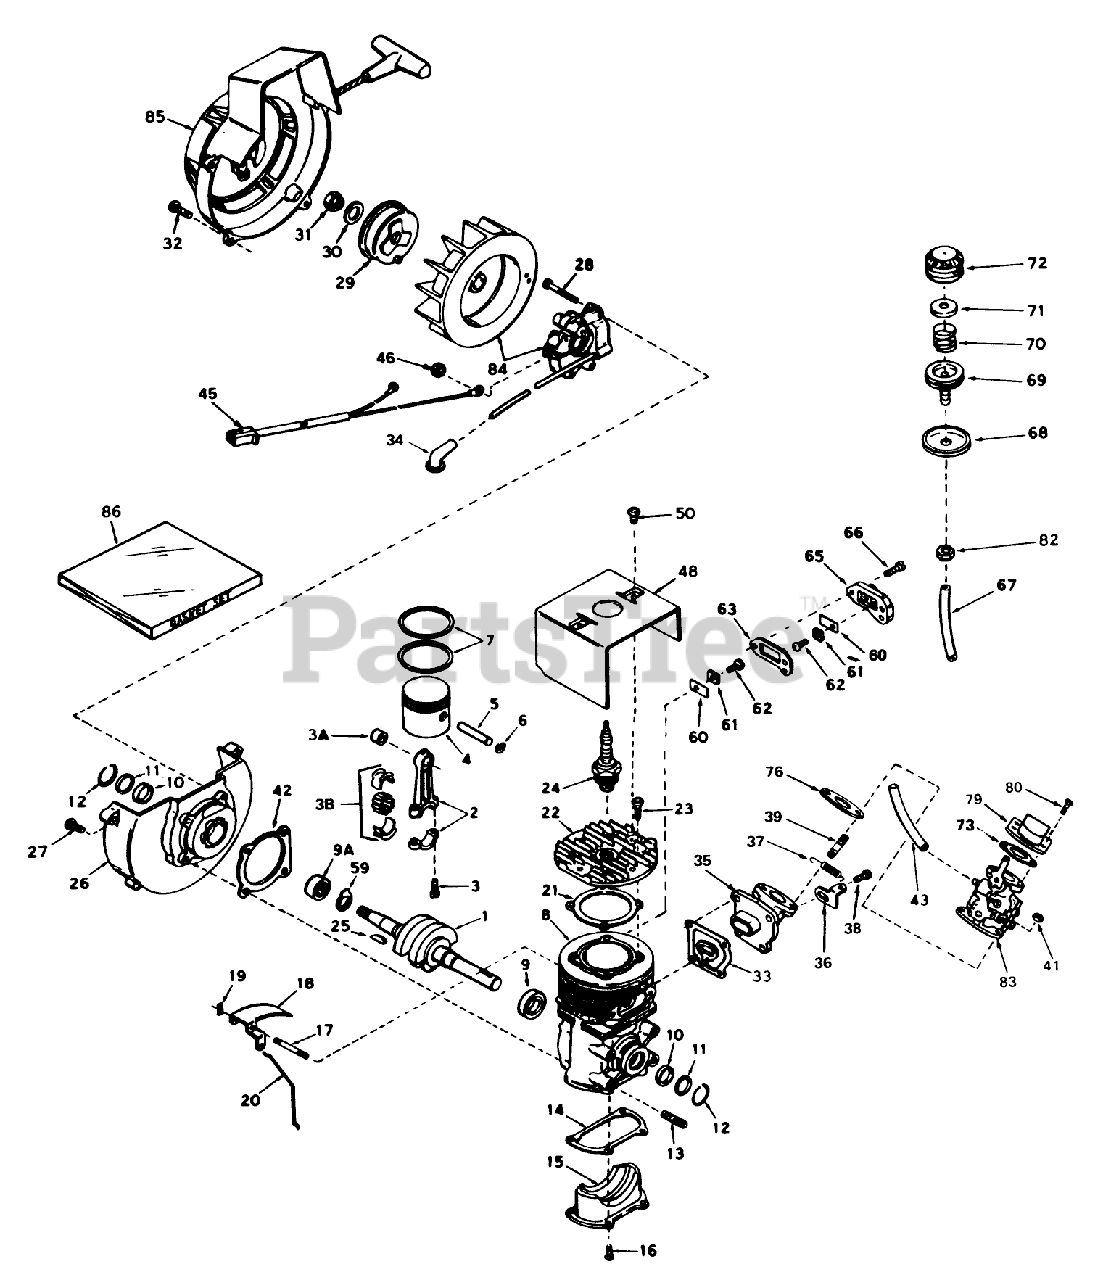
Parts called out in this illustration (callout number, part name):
1	Crankshaft
2	Rod Assembly, Connecting (Incl. #3, 3A 3B)
3	Bolt-Rod, Connecting
3A	Bearing-Cartridge
3B	Bearing Liner Set Needle
4	Piston
5	Pin, Piston
6	Ring-Retaning
7	Ring Set
8	Block Assy., Cylinder (Incl. Nos. 9, 10 thru 13 17)
9	Bearing Ball
9A	Bearing-Cartridge
10	Seal, Crankshaft
11	Retainer, Crankshaft Seal
12	Spring, Crankshaft Seal
15	Plate, Cover
16	Screw (T-25, 10-24 x 1/2)
17	Shaft, Air Vane
18	Vane Assy, Air
19	Clip,Air Vane
20	Link, Governor
23	Screw (T-30, 1/4-20 x 3/4)
24	Plug, Spark (J17LM or equiv.)
25	Key, Woodruff
26	Base Assy., Shroud (Incl. #9A-12)
27	Screw
28	Screw
29	Cup, Starter
30	Washer, Flat
31	Nut, Flywheel
32	Screw (T-30, 1/4-20 x 3/4)
34	Cover, Spark plug
35	Elbow Assy., Adapter
36	Lever, Adjusting
37	Spring, Adjusting Lever
38	Screw
41	Locknut
43	Line-Fuel
45	Harness, Wire
46	DECAL
48	Shroud, Cylinder
50	Screw (1/4-20 x 1/2)
59	Washer, Thrust
60	Reed, Compression Release
61	Plate, Reed Hold Down
62	Screw
65	Cover, Compression Release
66	Screw
67	Line, Primer
68	Retainer, Primer Bulb
69	Body, Primer
70	Spring, Primer Bulb
71	Washer, Primer Bulb
72	Bulb, Primer
73	Gasket
79	Baffle-Carburetor
80	Screw
82	Hex nut
83	Carburetor (Incl. #76)
84	BRACKET S
85	Shroud Starter Assy.
